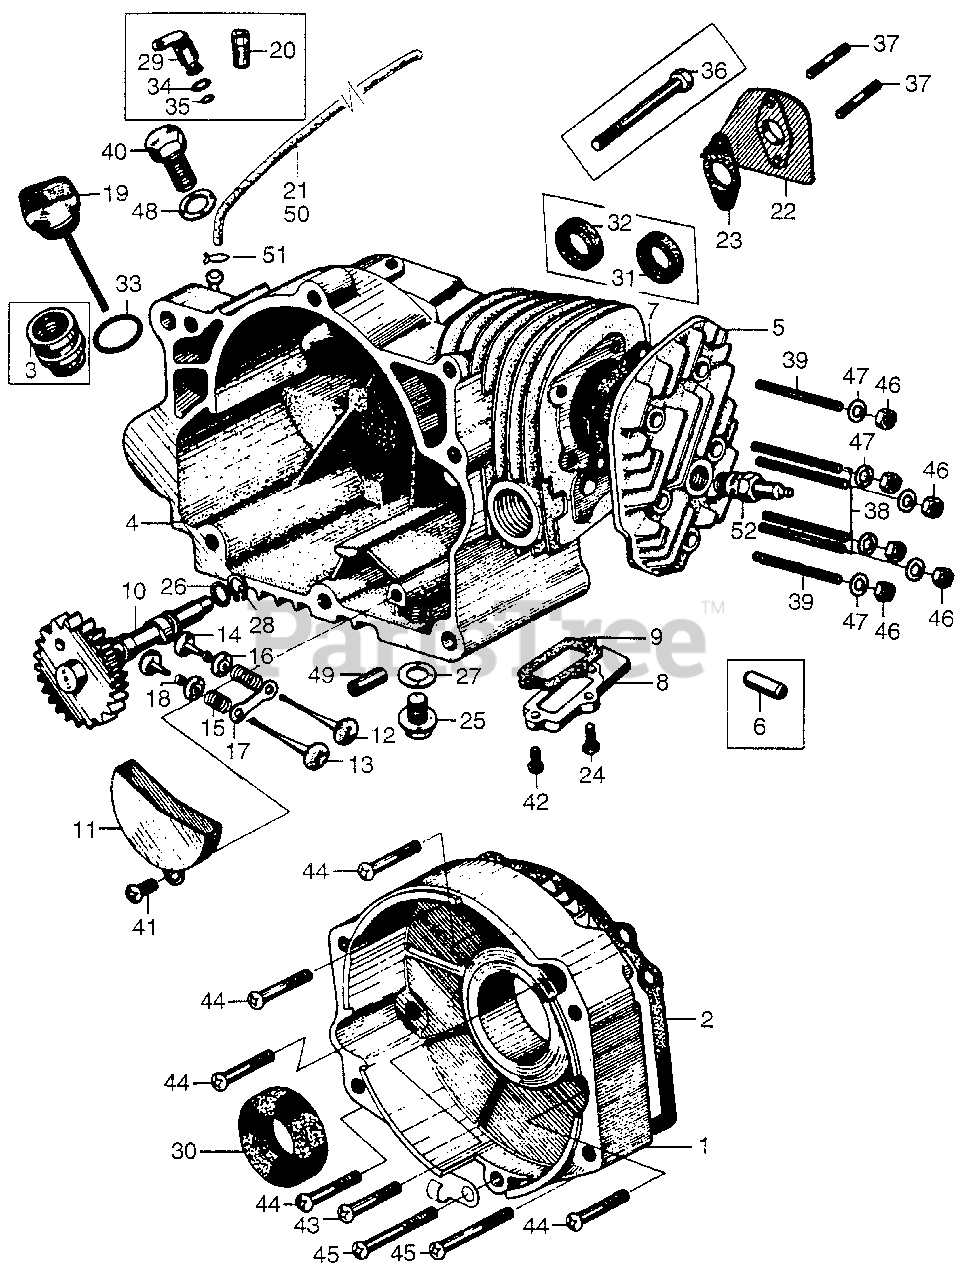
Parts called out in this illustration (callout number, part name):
1	COVER, CRANKCASE
2	GASKET, CRANKCASE COVER
5	CYLINDER HEAD
6	GUIDE, VALVE (OS) (NOT AVAILABLE)
7	GASKET, CYLINDER HEAD
8	COVER, TAPPET
9	GASKET, TAPPET COVER (NOT AVAILABLE)
11	PROTECTOR, GEAR (NOT AVAILABLE)
12	VALVE, IN. (NOT AVAILABLE)
13	VALVE, EX. (NOT AVAILABLE)
14	LIFTER, VALVE (NOT AVAILABLE)
15	SPRING, VALVE (NOT AVAILABLE)
16	RETAINER, VALVE SPRING (NOT AVAILABLE)
17	SEAT, SPRING (NOT AVAILABLE)
18	ADJUSTER C, TAPPET CLEARANCE (3.42-3.45) (NOT AVAILABLE)
18	ADJUSTER F, TAPPET CLEARANCE (3.33-3.36) (NOT AVAILABLE)
18	ADJUSTER, TAPPET CLEARANCE (3.24-3.27) (NOT AVAILABLE)
18	ADJUSTER, L. TAPPET CLEARANCE (3.15-3.18)
18	ADJUSTER, TAPPET CLEARANCE (3.06-3.09)
19	CAP, OIL (NOT AVAILABLE)
19	CAP, OIL
22	INSULATOR, CARBURETOR (NOT AVAILABLE)
23	GASKET, CARBURETOR INSULATOR (NOT AVAILABLE)
24	BOLT, SPECIAL (5MM)
25	BOLT, DRAIN PLUG (12MM)
26	WASHER (18MM)
28	CIRCLIP (18MM)
30	OIL SEAL (17X35X6)
31	OIL SEAL (18X28X5) (AJ-TYPE)
32	OIL SEAL (15X24X5)
37	BOLT, STUD (5X32) (NOT AVAILABLE)
38	BOLT, STUD (6X45) (SOURCE: VINTAGE PARTS INC.)
39	BOLT, STUD (6X50)
41	SCREW, PAN (5X10)
42	SCREW, PAN (5X18)
43	SCREW, PAN (5X22)
44	SCREW, PAN (5X22)
45	SCREW, PAN (5X36) (NOT AVAILABLE)
46	NUT, HEX. (6MM)
47	WASHER, PLAIN (6MM)
48	WASHER, DRAIN PLUG (14MM)
49	PIN A, DOWEL (8X14)
50	BULK HOSE, FUEL (4.5X3000) (4.5X185)
50	BULK HOSE, FUEL (4.5X3000) (4.5X210)
51	CLIP, TUBE (B8)
52	SPARK PLUG (CM6) (NGK)
